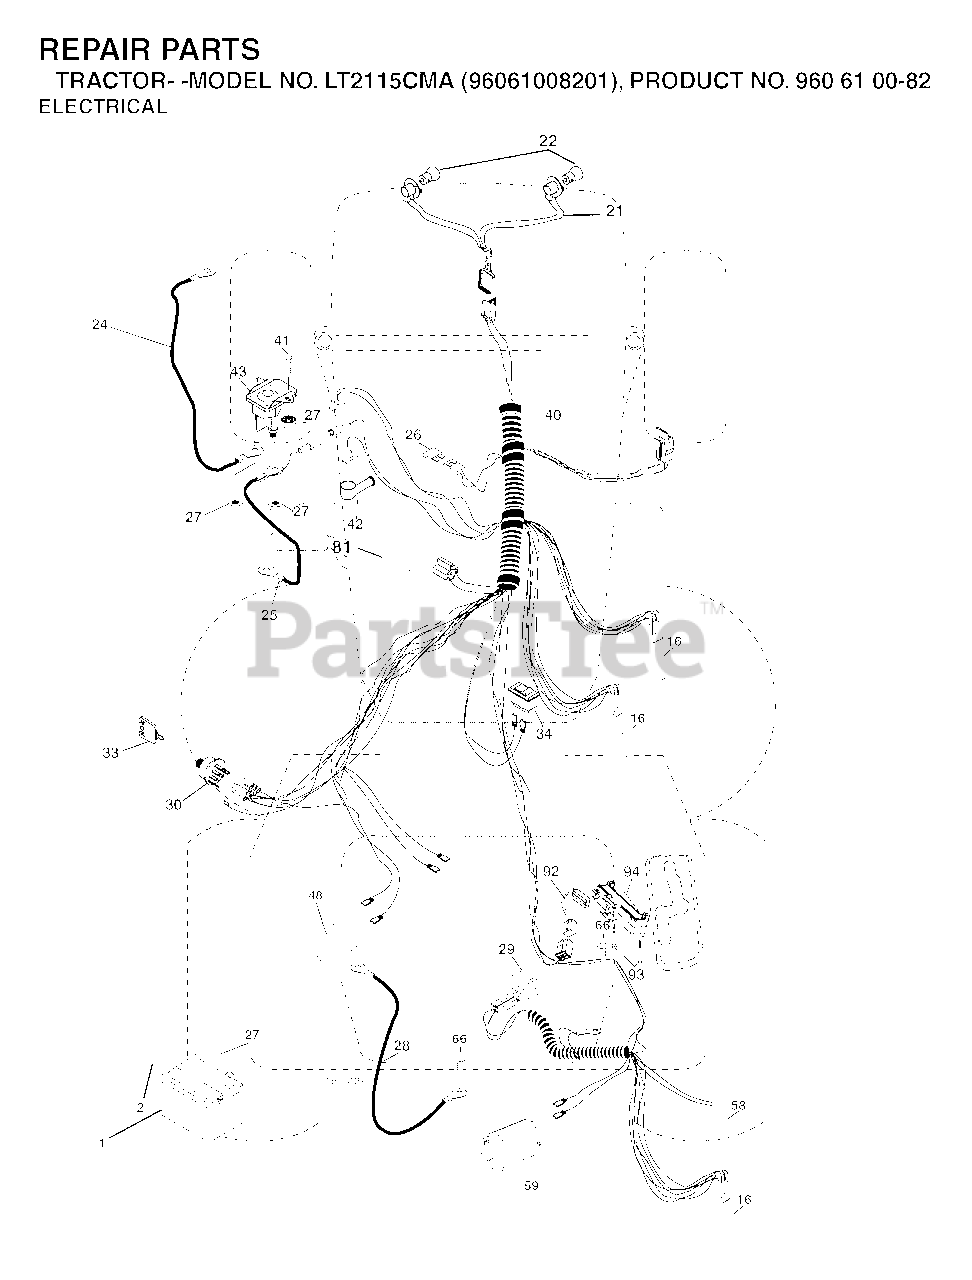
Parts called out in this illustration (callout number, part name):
1	BATTERY 12V .35 AMP
16	SWITCH INTERLOOK PUSH-IN
21	HARNESS ASSY LIGHT
22	LIGHTBULB
24	CABLE ASM
25	CABLE BATTERY
26	FUSE 20AMP
27	NUT
28	CABLE GROUND
29	SWITCH.SEAT.DP W/RAMPS
30	SWITCH.IGN.DELTA.W.LGH.ROS
33	KEY MLD GEN DELTA
34	SWITCH LT
42	TERMINAL COVER
43	SOLENOID.W/BRASS.PLUNG
58	BUZZER
81	RELAY.ASSY.T
92	HARNESS.PIGTAIL.CONSLE
93	SCREW.PLASTITE
94	MODULE.REVERSE.ROS
